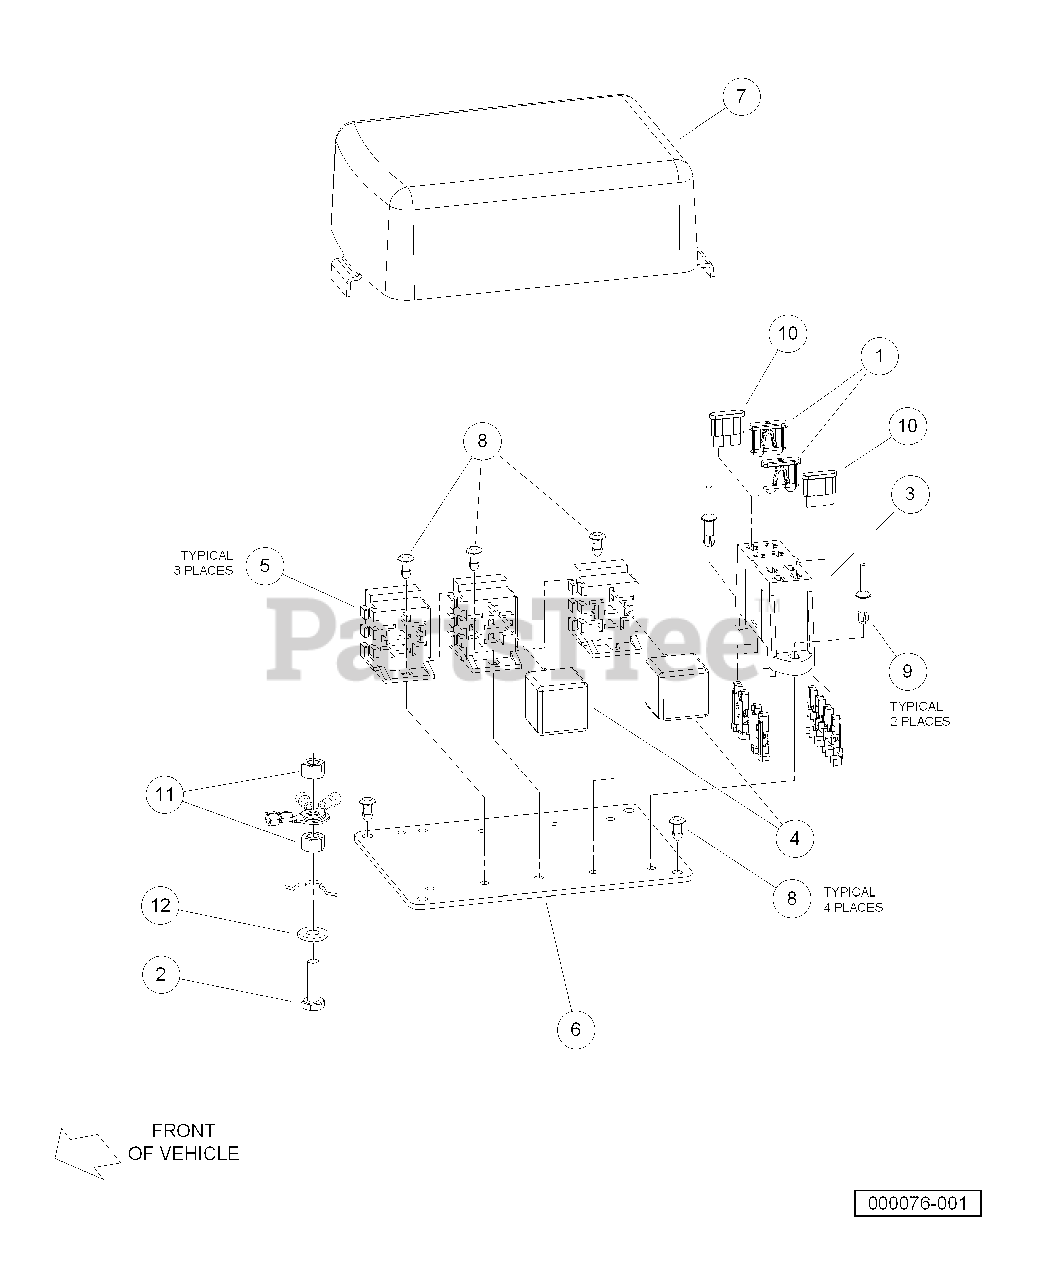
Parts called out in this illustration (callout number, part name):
1	Fuse, 10-Amp
2	Screw, 1/4-20 X .88 Hex Hd Cap
3	Fuse Block
4	Relay, Mini ISO, SPDT
5	Connector, Relay
6	Plate, Electrical
7	Cover, Electrical
8	Fastener, Push-in
9	Rivet, Drive
10	Fuse, 25-Amp.
11	Locknut, 1/4-20 Dimpled
12	Washer, 1/4 Type A Narrow Flat
